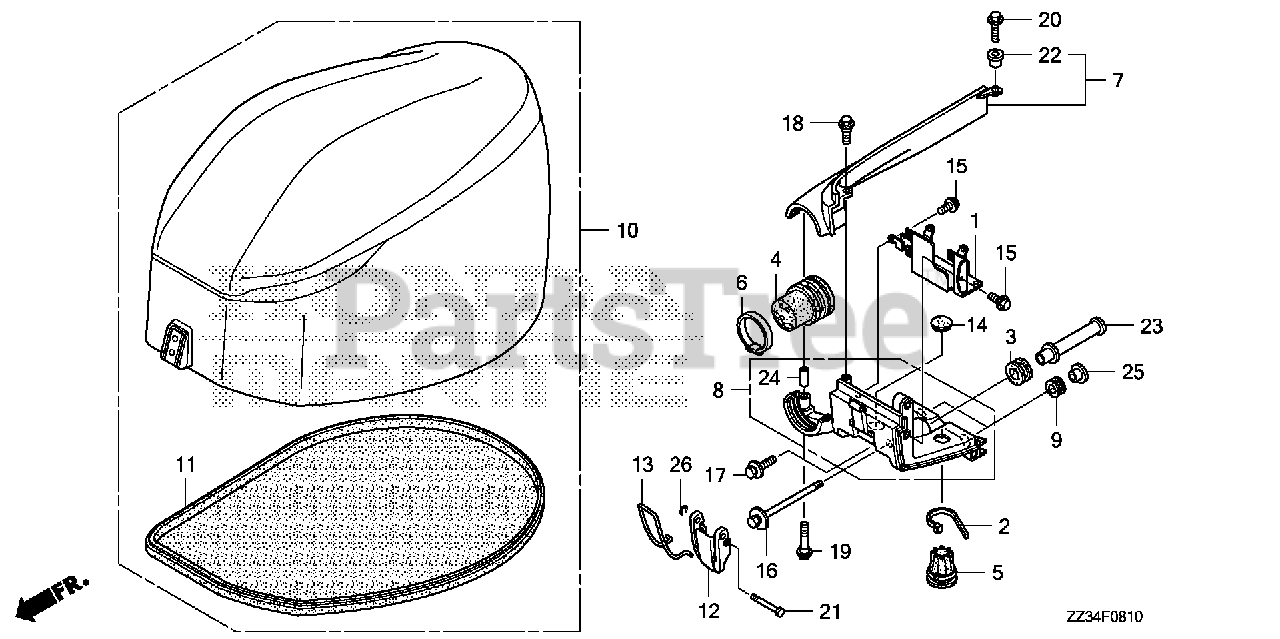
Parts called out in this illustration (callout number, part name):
1	BRACKET, REMOTE CONTROL CABLE
2	BAND (BLACK 3.5X140)
3	GROMMET, CASE (LOWER)
4	GROMMET, REMOTE CONTROL CABLE
5	GROMMET, CASE (LOWER) (C)
6	BAND, CASE GROMMET (LOWER)
7	COVER, FR. SEPARATE *NH282MU* (OYSTER SILVER METALLIC-U)
8	BRACKET, FR. COVER (LOWER) *NH282MU* (OYSTER SILVER METALLIC-U)
9	RUBBER, FENDER MOUNTING
10	COVER ASSY., ENGINE *NH282MU* (OYSTER SILVER METALLIC-U)
11	SEAL, ENGINE COVER
12	LEVER, FASTENER
13	WIRE, FASTENER
14	CAP, L. SIDE COVER
15	BOLT, FLANGE (6X10)
16	BOLT-WASHER (6X95)
17	BOLT-WASHER (6X27)
18	BOLT, SPECIAL (6X17)
19	BOLT, SPECIAL (6X37)
20	BOLT, FLANGE (6X20)
21	PIN (5X44.5)
22	COLLAR, DISTANCE (6.5X9X11.5)
23	COLLAR, FR. BRACKET
24	COLLAR, DISTANCE (6.1X9.1X20.5)
25	COLLAR, DISTANCE (6.2X7.5)
26	E-RING (4MM)
